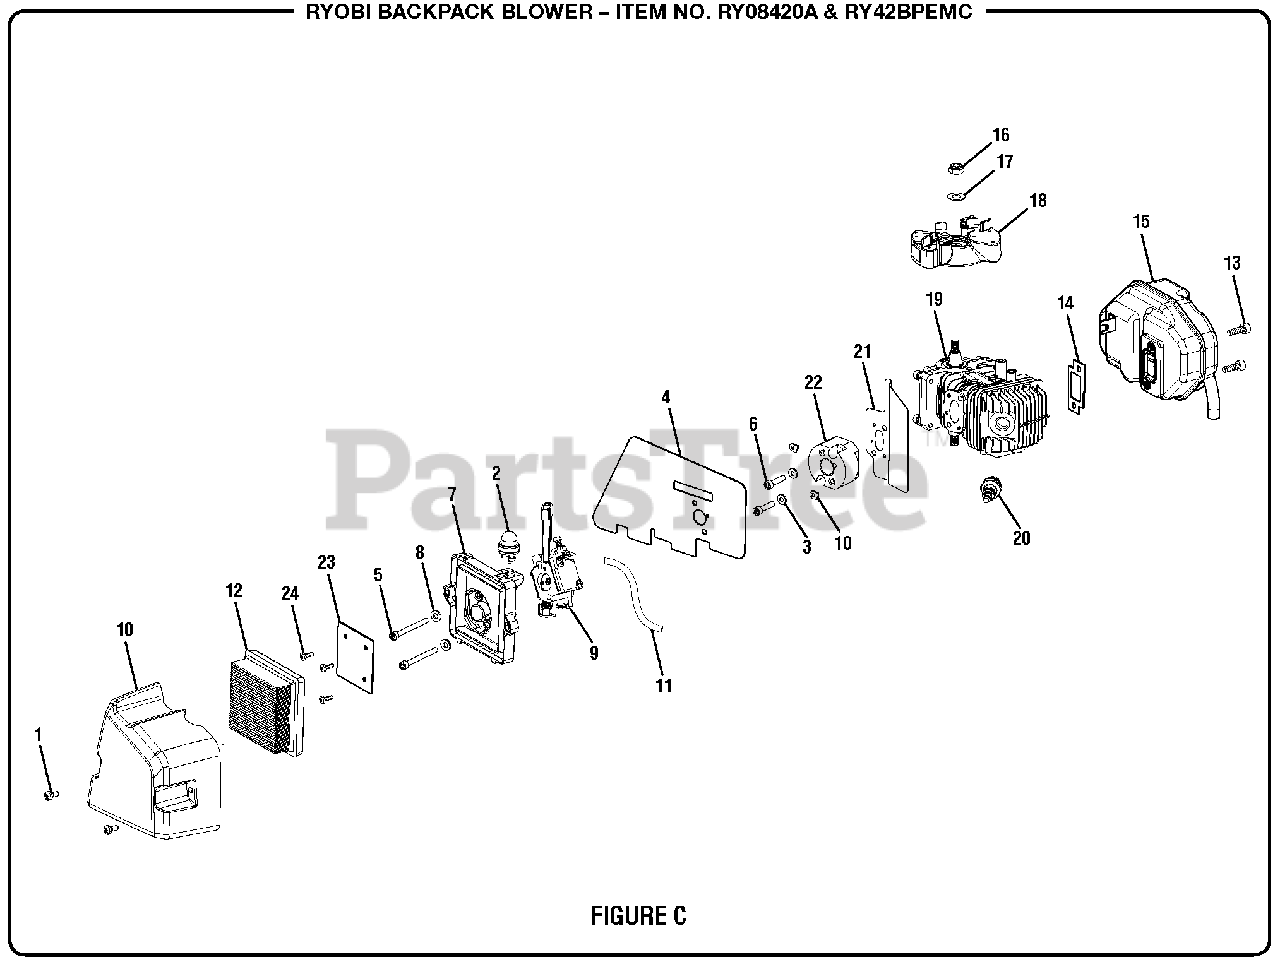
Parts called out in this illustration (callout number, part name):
1	Screw (M5, Special)
2	Primer Assembly
3	Spring Washer (M5)
5	Screw (M5 x 50 mm, Soc. Hd.)
6	Screw (M5 x 0.8 in.)
7	Air Box Kit w/Labels
8	Washer (ID5.8 x OD11.5 x 1.7t)
9	Carburetor (Walbro, WT-1086)
10	Washer (Heat Dam)
11	Fuel Line
12	Air Filter
13	Bolt (1/4-20 x 18 mm)
15	Exhaust Assembly
16	Lock Nut (M8)
17	Washer (ID9 x OD17.7 x 1.1t)
18	Flywheel Assembly
19	Short Block Assembly
20	Spark Plug (RCJ4)
24	Screw (M4 x 12 mm, Pan Hd.)
